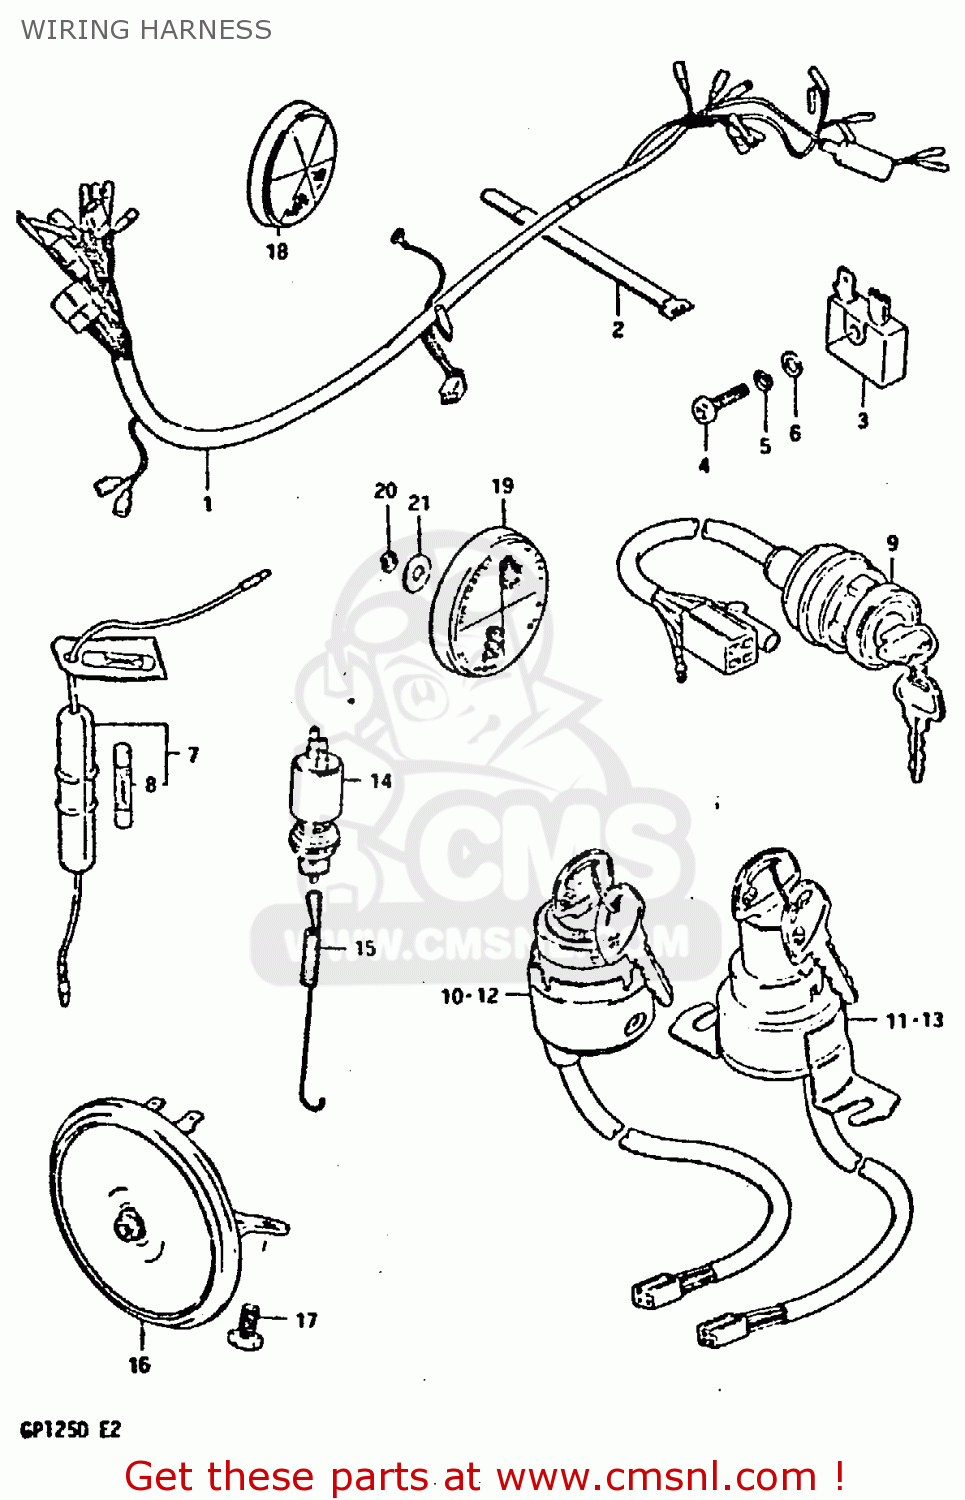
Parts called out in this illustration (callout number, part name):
1	WIRING HARNESS
2	CLAMP
3	RECTIFIER ASSEMBLY
4	SCREW 5X20
5	LOCK WASHER
6	WASHER
7	BOX ASSEMBLY,FUSE
8	FUSE(10A)
9	SWITCH ASSY, IGNITION
14	SWITCH ASSY,BRAKE LAMP
15	SPRING
16	HORN ASSY
17	BOLT
18	REFLEX REFLECTOR,FR
20	LOCK WASHER
21	WASHER
